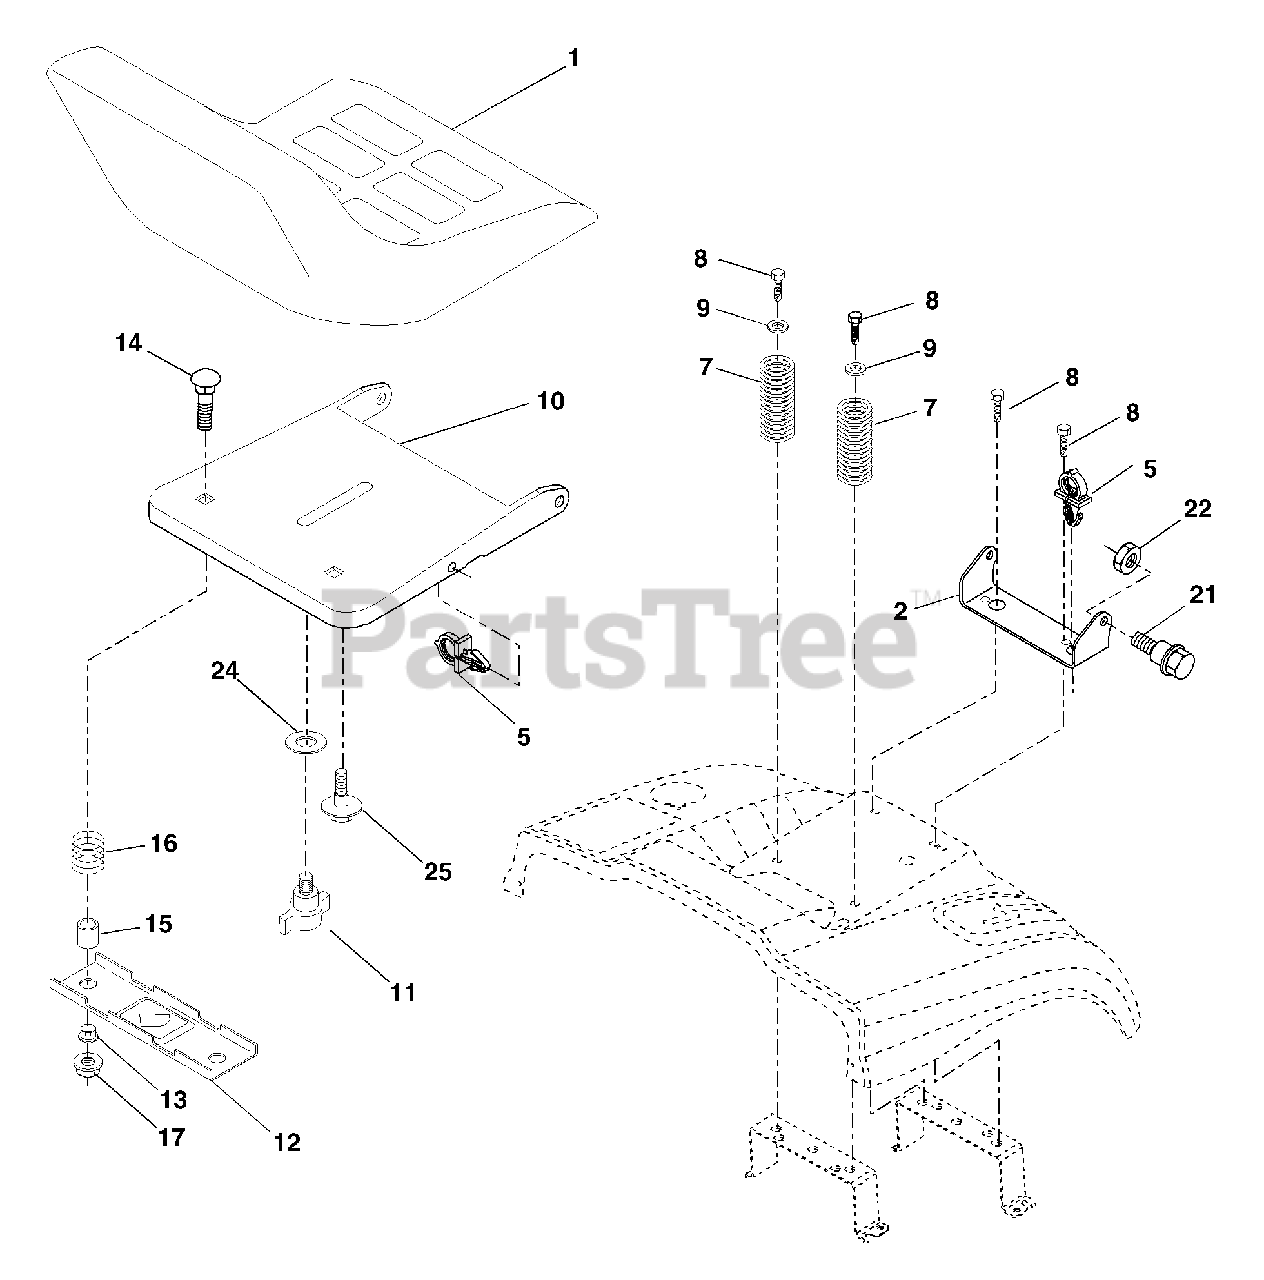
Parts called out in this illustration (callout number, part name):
1	Seat
2	Bracket Pnt Pivot Seat (blk )
5	Clip Push In Hinged
7	Spring Seat Cprsn 2 250 Blk Zi
8	Screw 3/8-16 X 1-1/2
9	Washer 13/32 X 1 X 14 Ga
10	Pan Pnt Seat (blk )
11	Knob Seat Adj. Wingnut
12	Bracket Pnt Mounting Switch
13	Bushing Snap Blk Nyl 50 Id
14	Bolt Rdhd Sht Nk 1/4-20x1-1/2
15	Spacer Split
16	Spring Cprsn Plate SW 1.310 Ga
17	Nut Lock 1/4 Lge Flg Gr 5 Zinc
21	Bolt Shoulder 5/16-18 Unc-2A
22	Nut Hex Lock w/Ins 5/16-18
24	Washer 17/32 X 1 X 12 Ga.
25	Bolt Shoulder 5/16-18 X 62
